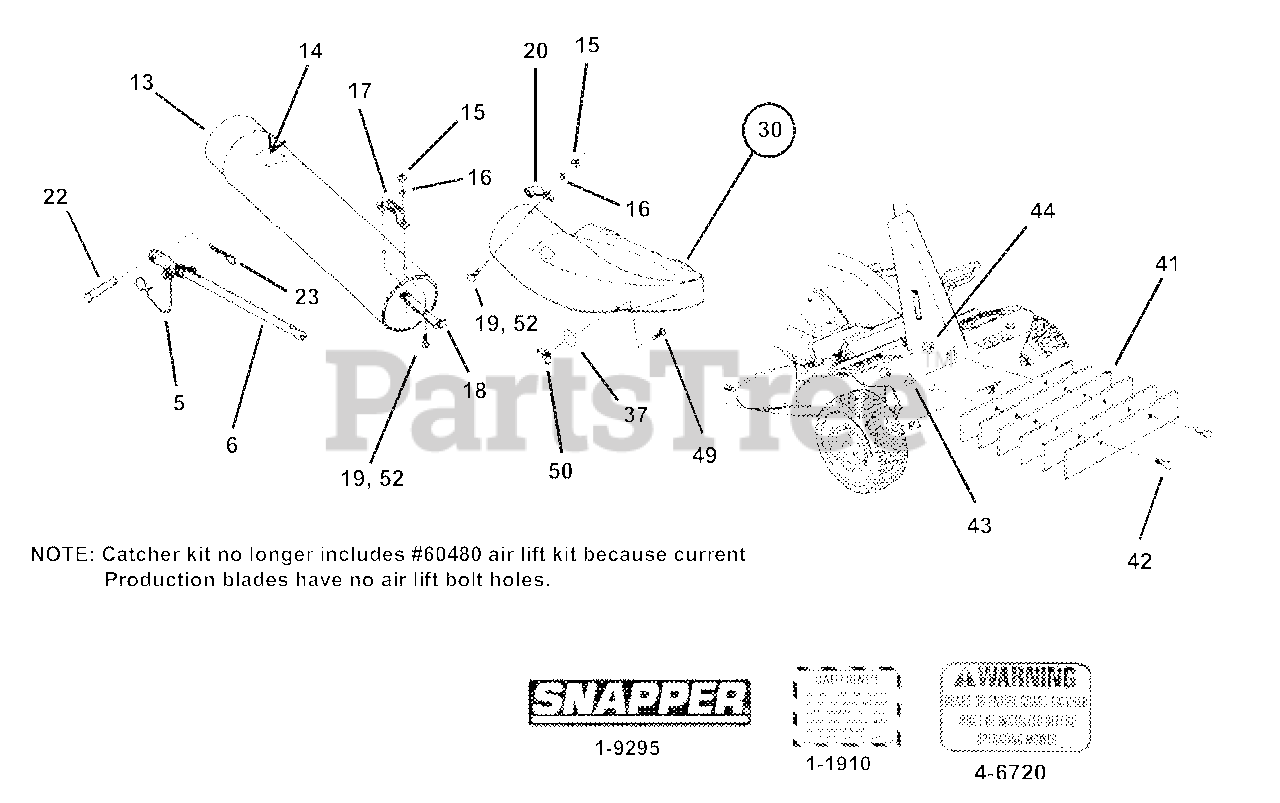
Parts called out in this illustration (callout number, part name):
1-1910	DECAL, GRASS CATCHER
1-9295	DECAL, SNAPPER
4-6720	DECAL, CHUTE DEFLECTOR
5	ASSEMBLY, Spring & Hook
6	BRACE, Rear (24-1/2" Long)
13	TUBE, Grass (36" long)
14	DECAL, Caution
15	NUT, 1/4-20 Hex
16	WASHER, 1/4 Internal Tooth Lock
17	HANDLE, Tube
18	BASE, Tube Handle
19	BOLT, 1/4-20 x 3/4" Carriage
20	LATCH, Tube Chute
22	PIN, 5/16 x 11/16" Clevis
23	PIN, 3/32 x 1-1/2" Hair
30	ADAPTER
37	WASHER, 5/16" Flat
41	WEIGHT, Front Frame
42	SCREW, 5/8-11 x 1-3/4" Cap
43	WASHER, 5/8" Split Lock
44	NUT, 5/8-11 Hex
49	BOLT, 5/16-18 x 1" Carriage
50	WING NUT, 5/16-18 Lock
52	SCREW, 1/4-20 x 3/4"
